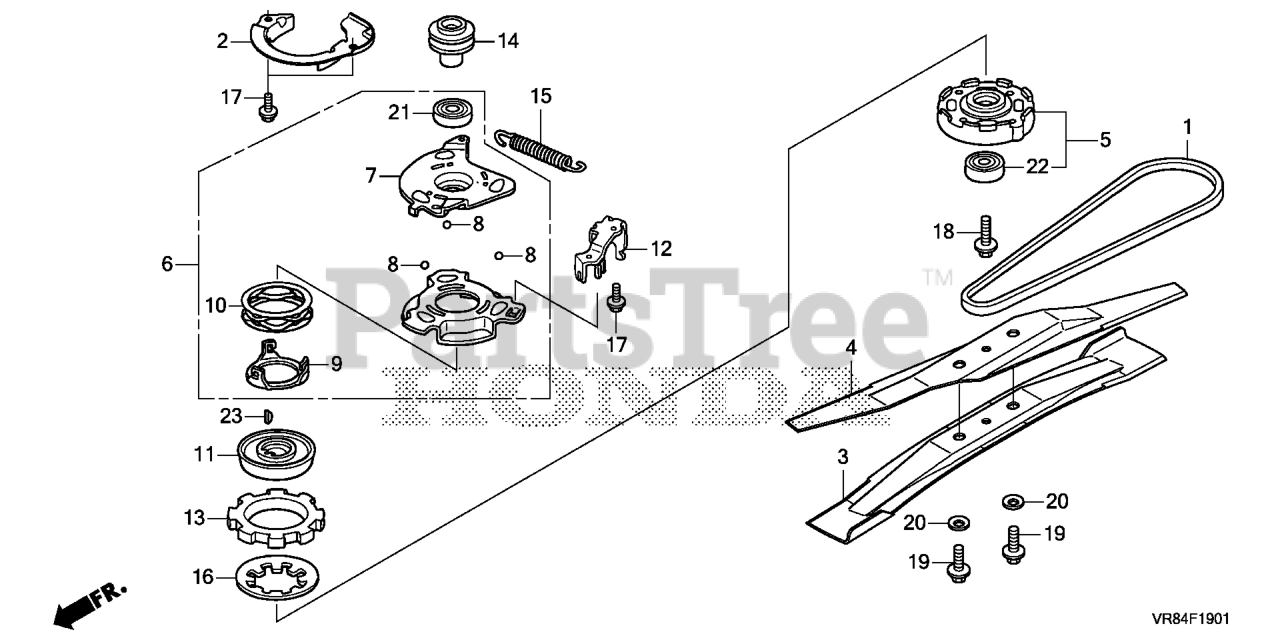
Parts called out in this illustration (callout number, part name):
1	V-BELT (3L-39.2)
2	GUIDE, ENGINE BELT
3	BLADE, ROTARY
4	BLADE, ROTARY (UPPER)
5	HOLDER ASSY., BLADE
6	PLATE ASSY., BALL CONTROL
7	PLATE, BALL CONTROL
8	BALL, STEEL
9	PLATE, SPRING HOOK
10	SPRING, BALL PLATE
11	DISK, DRIVE
12	HOOK, RETURN SPRING
13	DISK, DRIVEN
14	PULLEY, DRIVE
15	SPRING ASSY., CLUTCH RETURN
16	SPRING, CLUTCH
17	BOLT, FLANGE (6X14)
18	BOLT, FLANGE (10X24)
19	BOLT, HEX. (10X20)
20	WASHER, SPRING (10MM)
21	BEARING, RADIAL BALL (6006) (SST)
21	BEARING, RADIAL BALL (6006) (TSB)
22	BEARING, RADIAL BALL (6204)
23	KEY, WOODRUFF (16X15)
